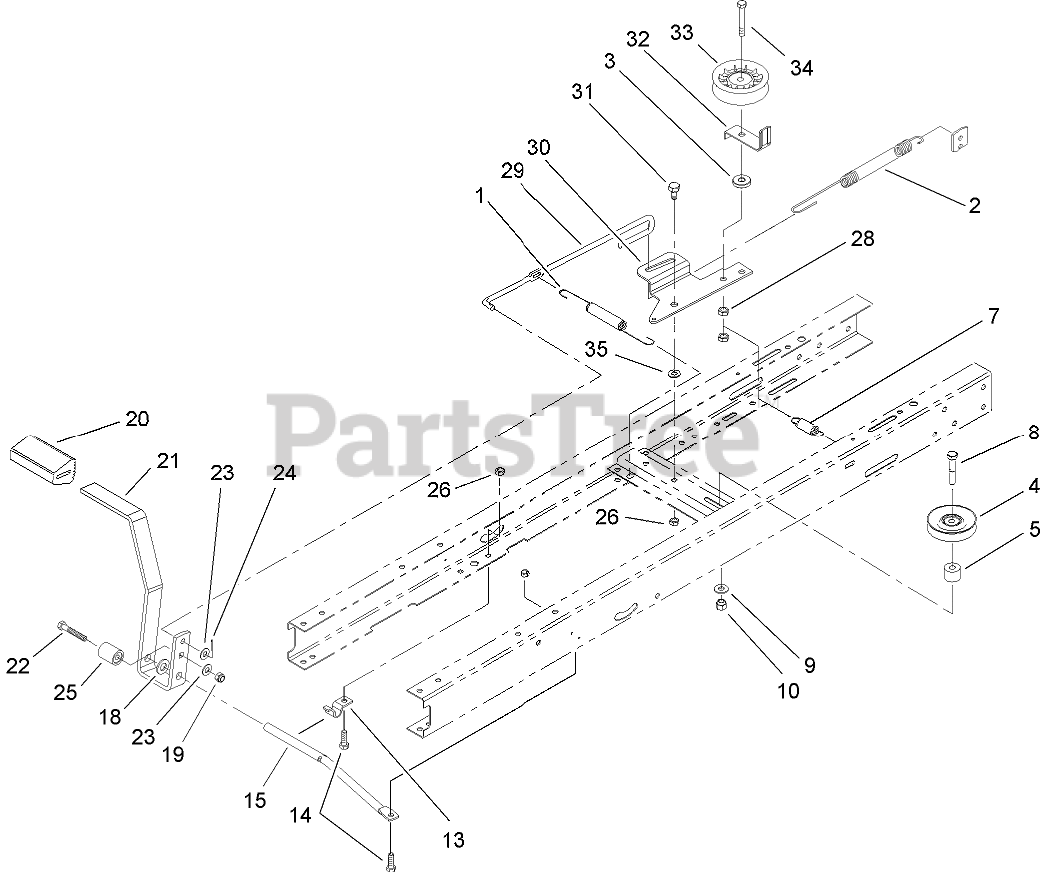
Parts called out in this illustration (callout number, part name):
1	SPRING-EXTENSION
2	SPRING-EXTENSION
3	WASHER
4	PULLEY-IDLER
5	SPACER
7	SPRING-EXTENSION
8	SCREW-HH
9	WASHER-FLAT
10	NUT-LOCK, NI
13	CLAMP-PIVOT, SHIFT
14	SCREW-HH
15	ROD-PIVOT, PEDAL
18	WASHER-FLAT
19	NUT-LOCK, NI
20	PAD-PEDAL
21	PEDAL-CLUTCH/BRAKE, HYDRO
22	SCREW-HH
23	WASHER-PLAIN
24	PIN-COTTER
25	SPACER
26	NUT-LOCK, NI
28	NUT-LOCK, NI
29	ROD-CLUTCH/BRAKE
30	ARM-IDLER
31	BOLT-SHOULDER
32	GUIDE-IDLER, BELT
33	PULLEY-IDLER
34	SCREW-HH
35	WASHER-PIVOT
